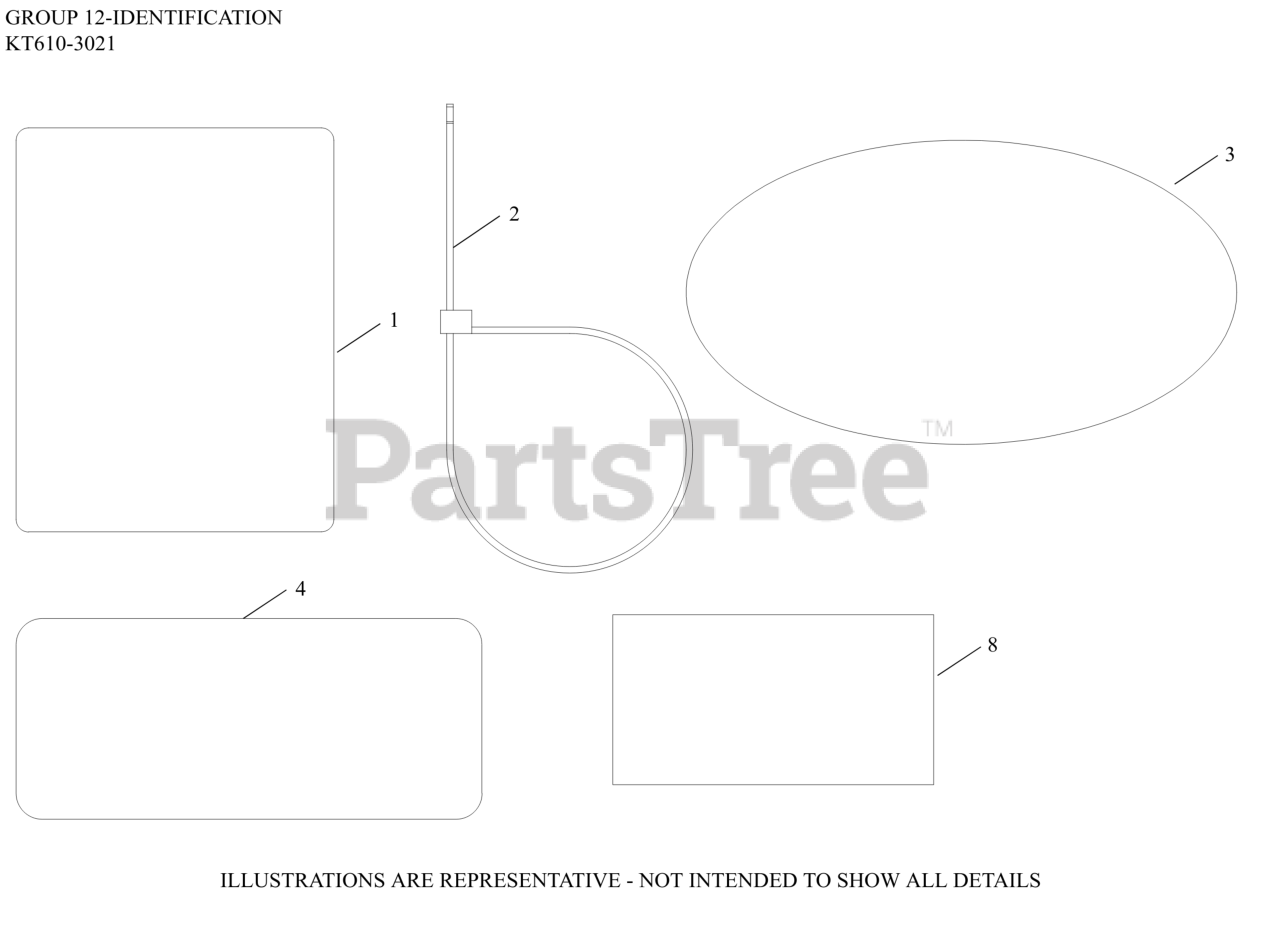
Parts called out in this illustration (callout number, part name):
1	LABEL, CLEAR LAMINATION
3	LABEL, 6600 SERIES (19HP)
4	LABEL, CANADIAN COMPLIANCE
8	DECAL, USA
